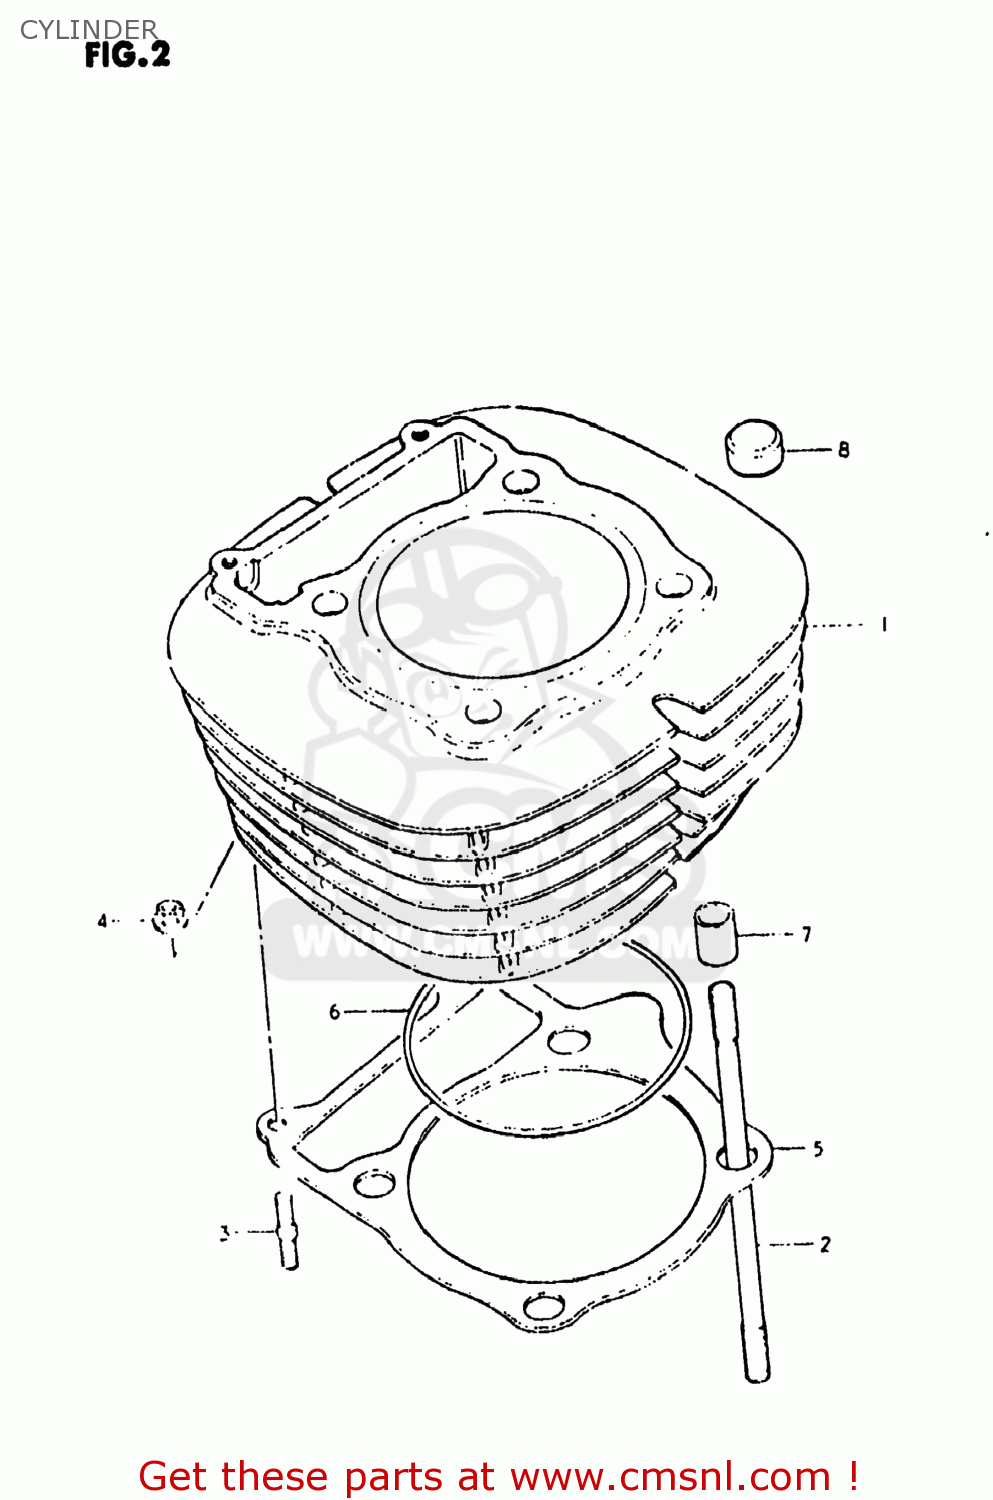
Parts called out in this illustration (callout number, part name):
1	CYLINDER
2	STUD
3	STUD 6X20
4	NUT
5	GASKET,CYLINDER (MCA)
6	O RING(D:2,ID:87)
7	PIN
8	PAD,CYLINDER HEAD
